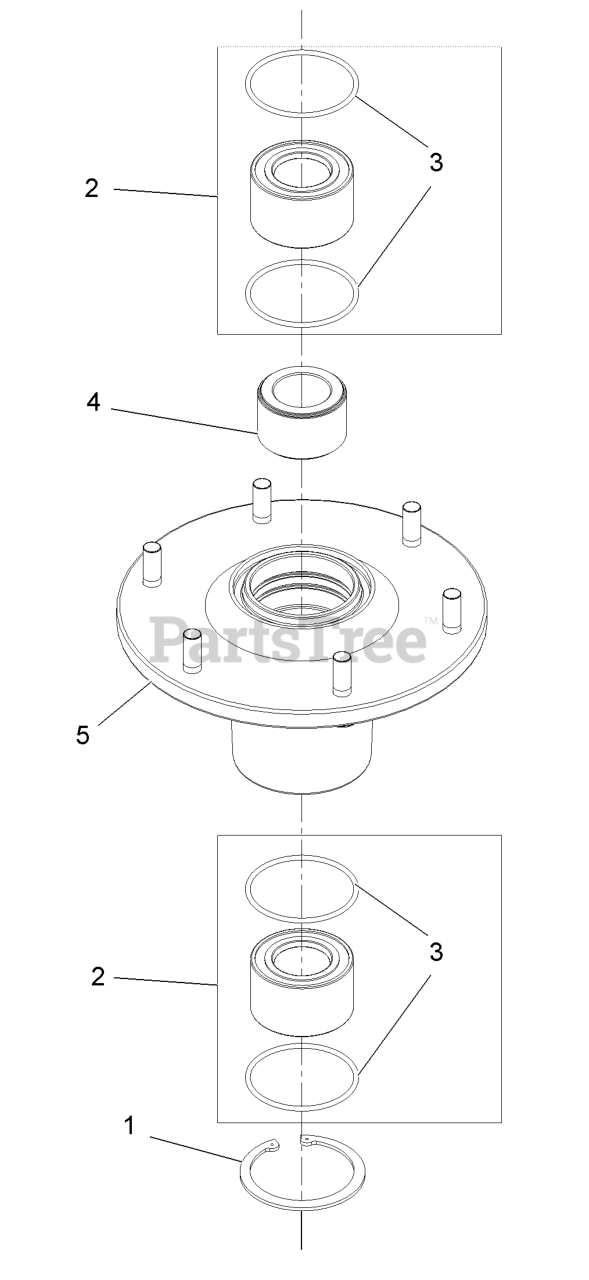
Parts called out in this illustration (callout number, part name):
1	RING-RETAINING
2	ASM, BEARING W/ORINGS
4	SPACER,BEARING
5	ASM,HOUSING W/STUDS
